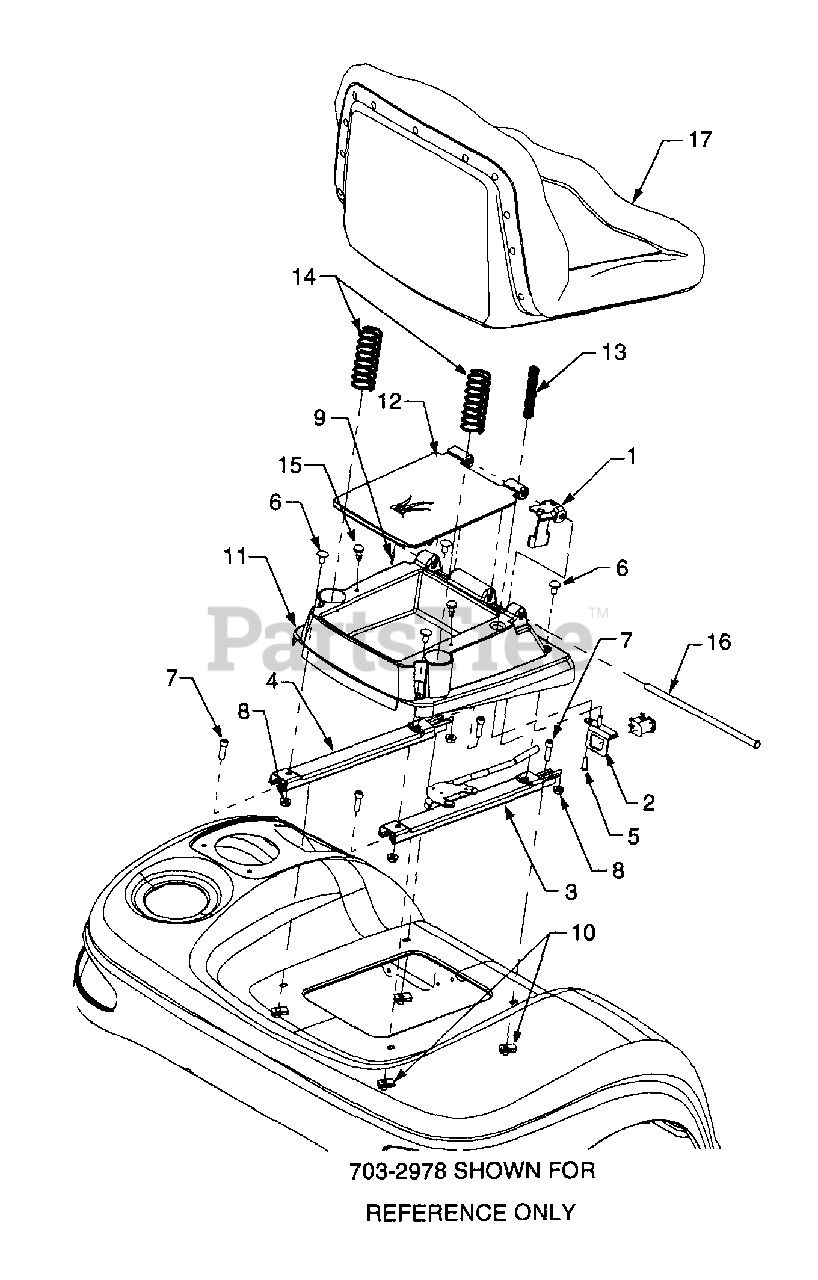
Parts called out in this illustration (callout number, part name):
1	Bracket, Seat Switch
2	Bracket, Switch Mounting
3	Track, Seat, w/Latch
4	Track, Seat, w/o Latch
5	Screw, Pan Torx Hd., #12-14 x .5
6	Carriage Bolt, 5/16-18 x .62
7	Screw, Pan Torx Hd. 5/16-18 x 1.0
8	Nut, Hex Flange Lock, 5/16-18
9	Pin, Cotter, 3/32 x .75
10	Speed Nut, U-Type, 5/16-18
11	Base, Seat
12	Lid, Tlbx
13	Spring, Compression
14	Spring, Compression
15	Bumper
16	Rod, Seat Pivot
17	Seat, High Back
